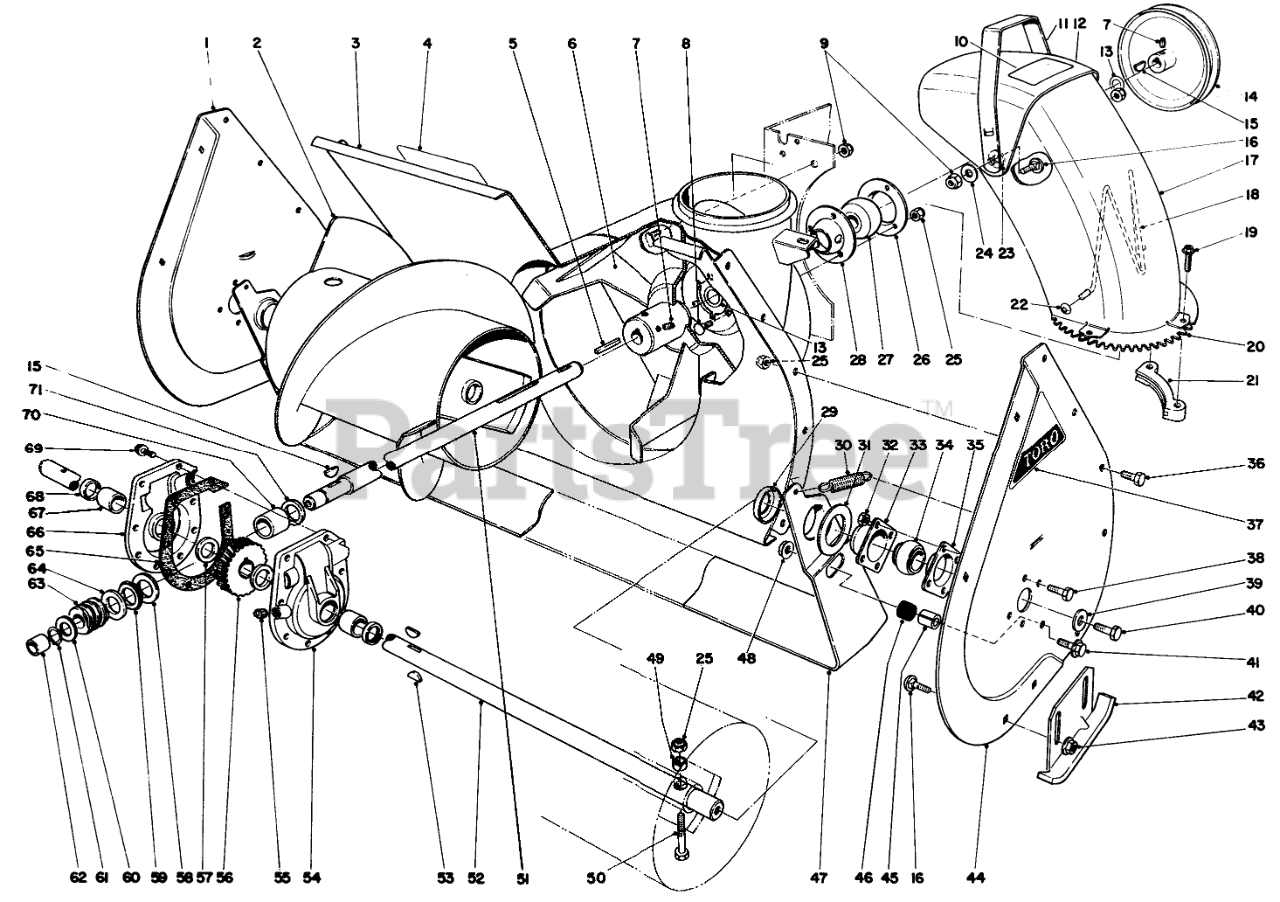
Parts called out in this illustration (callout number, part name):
1	RH AUGER SIDE PLT R
2	Auger Right
3	AUGER HSG WA RO
4	Decal-Warning
6	IMPELLER WA RO
7	SCREW-SET, SQH
8	BOLT-CARR
9	NUT-LOCK, CONE
10	Decal-Danger
11	DEFLECTOR HANDLE B
12	Deflector Chute (Incl. Ref. #10)
13	WASHER
14	IMPELLER PULLEY
15	KEY-WOODRUFF
16	SCREW-CARR
17	Chute
18	WIRE-CHUTE
19	SPECIAL SCREW
20	Gear-Chute Swivel
21	CHUTE RETAINER
22	NUT-PUSH
23	WASHER-RUBBER
24	WASHER-BELLEVILLE
25	NUT-LOCK, NI
26	FLANGE-CUP, BEARING
27	Ball Bearing
28	FLANGE-CUP, BEARING
29	Positioner-Scraper
30	SPRING-TENSION
31	SCRAPER BLADE SPACER
32	NUT-LOCK, CONE
33	BEARING-FLANGE, FRONT
34	BEARING
35	BEARING-FLANGE, REAR
36	SCREW-HH
37	AUGER SIDE PLT DECAL
38	SCREW-HH
39	WASHER
40	SCREW-HH
41	SCREW-HHF
42	AUGER SKID WA R
43	NUT-HHF, WHIZ
44	LH AUGER SIDE PLT R
45	SCRAPER STOP SPACER
46	SCRAPER STOP CUSHION
47	24 SCRAPER BLD
48	NUT-HF
49	SPACER-HUB, AUGER
50	Auger Bolt
51	Shaft Impeller
52	24 AUGER SHAFT
53	KEY-WOODRUFF
54	Gear Case (Incl. Ref. #67 & 68)
55	PLUG-PIPE, SQH
56	GEAR-WORM, 27T
57	WASHER-THRUST
58	WASHER-THRUST
59	BEARING-THRUST
60	WASHER-THRUST
61	Ring-Snap
62	BUSHING
64	THRUST-WASHER
65	GASKET-CASE, GEAR
66	Gear Case (Incl. Ref. #67 & 68)
67	BUSHING
68	SEAL-OIL
69	SCREW-TAPTITE
70	BUSHING-SPECIAL
71	RING-QUAD
